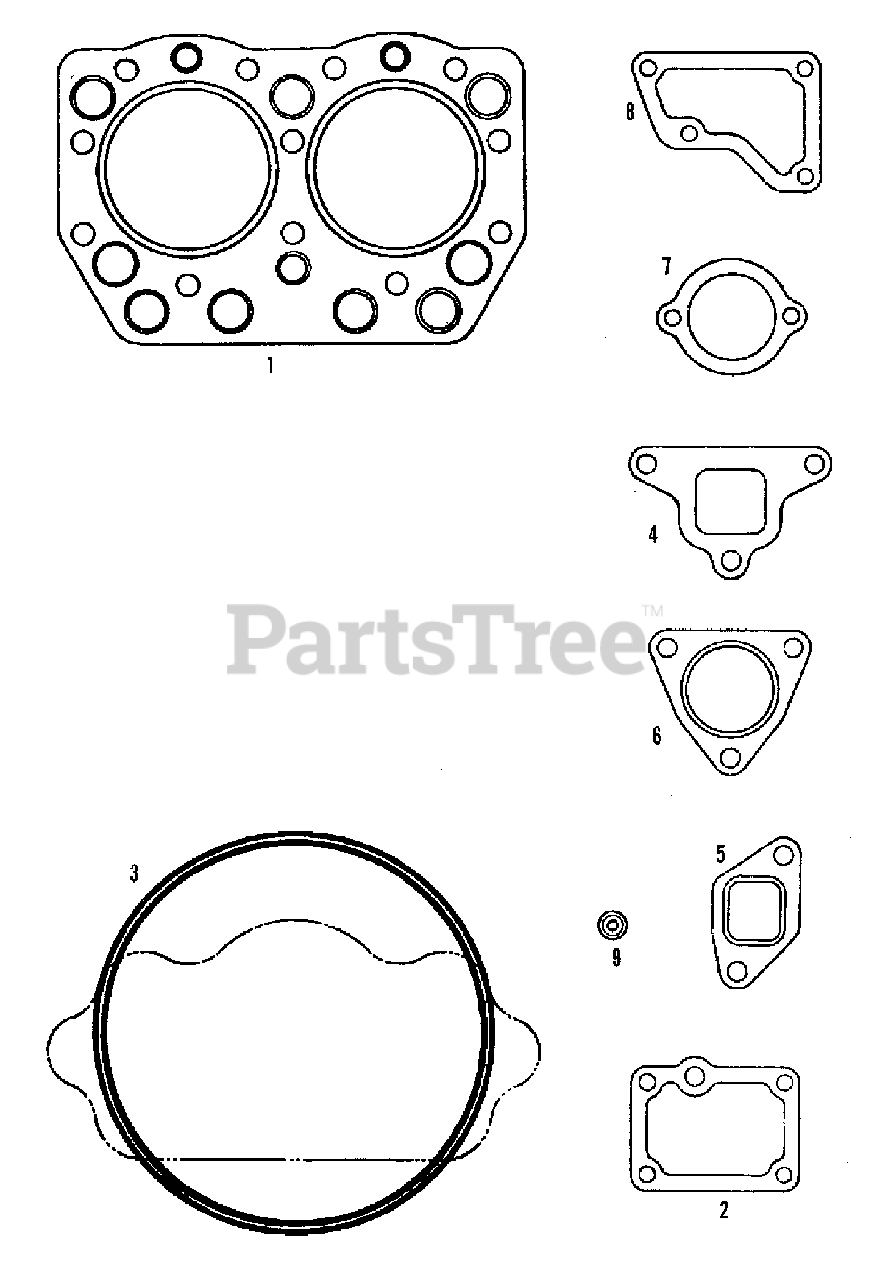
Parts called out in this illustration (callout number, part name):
1	GASKET, cylinder head
2	GASKET, water cover
3	GASKET, Cover, cylinder head
4	GASKET, intake manifold
5	GASKET, exhaust manifold
6	GASKET, diffuser
7	GASKET, water outlet
8	GASKET, water inlet
9	GASKET, fuel injector
